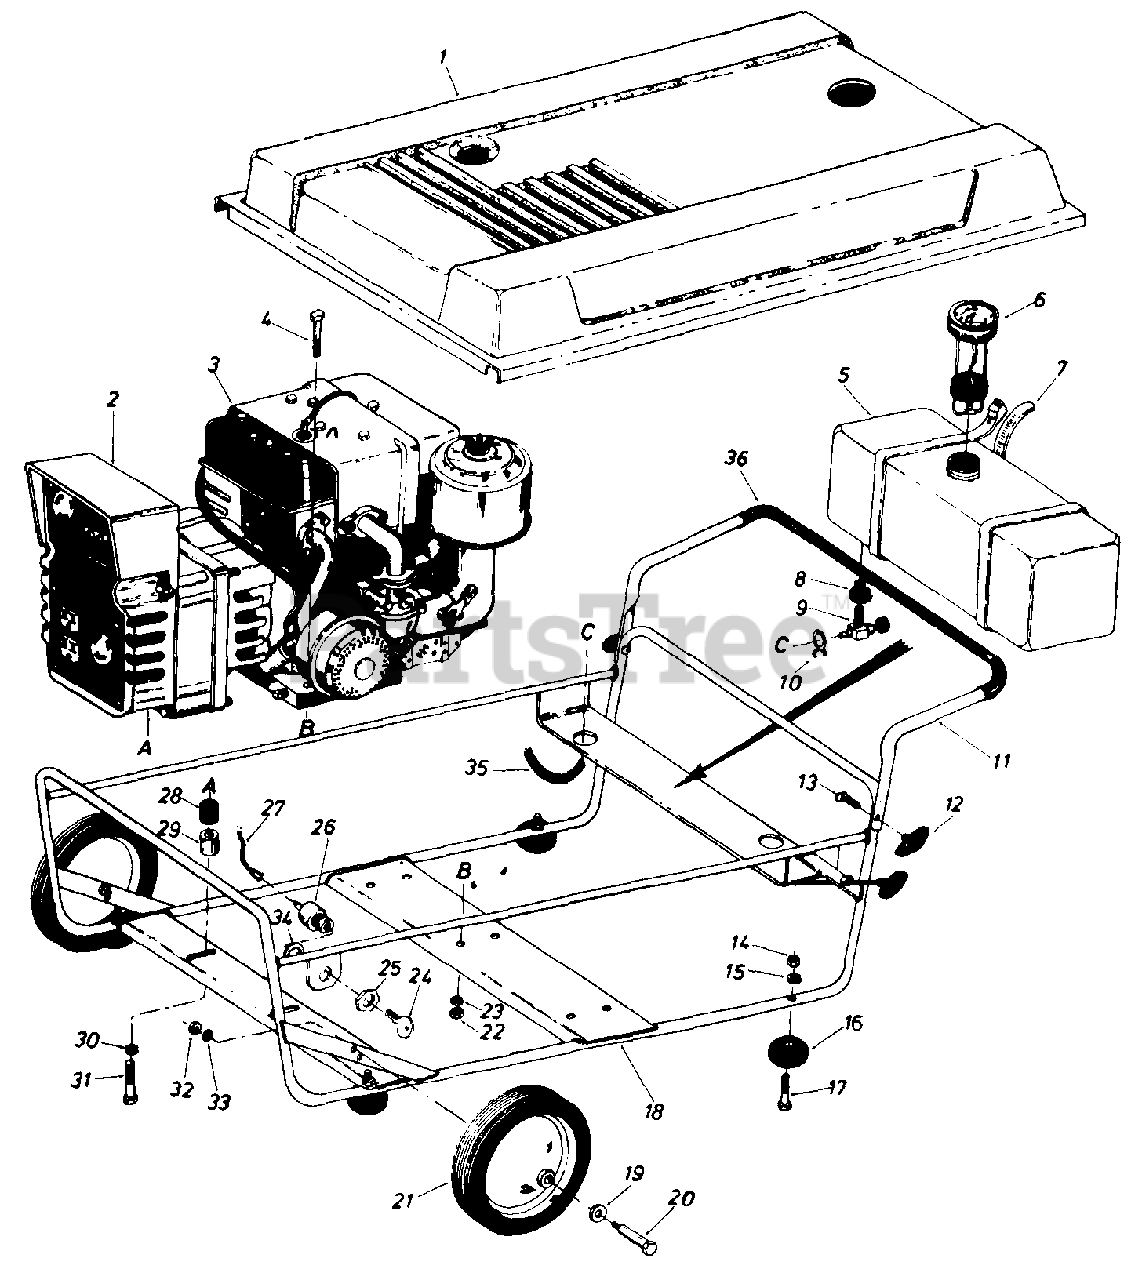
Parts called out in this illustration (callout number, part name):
1	Cover
2	Generator
3	Engine
4	Hex Bolt 5/16-18 x 1.75" Lg.
7	Cable Tie
8	Bushing
9	Fuel Shut Off Valve w/Filter
10	Hose Clamp
11	Upper Handle
12	Hand Knob
13	Curved Hd. Carriage Bolt 5/16-18 x 1.75" Lg.
14	Hex Nut 1/4-20 Thd.
15	L.-Wash. 1/4" I.D.
16	Rubber Bumper
17	Truss Mach. Scr. 1/4-20 x 1.75" Lg.
18	Carriage Ass'y.
19	Fl.-Wash. .625" I.D. x .943" O.D.
20	Shoulder Bolt .623 Dia. x 2.75" Lg.
21	Wheel Ass'y.-Comp. 10 x 1.75
22	Hex Nut 5/16-18 Thd.
23	L.-Wash. 5/16" I.D.
24	Ignition Key
26	Ignition-Safety Switch
27	Electric Wire
28	Rubber Bumper
30	L.-Wash. 5/16" I.D.
31	Hex Sems Bolt 5/16-18 x .62" Lg.
32	Hex Nut 3/8-16 Thd.
33	L.-Wash. 3/8" I.D.
35	Fuel Line 29" Lg.
